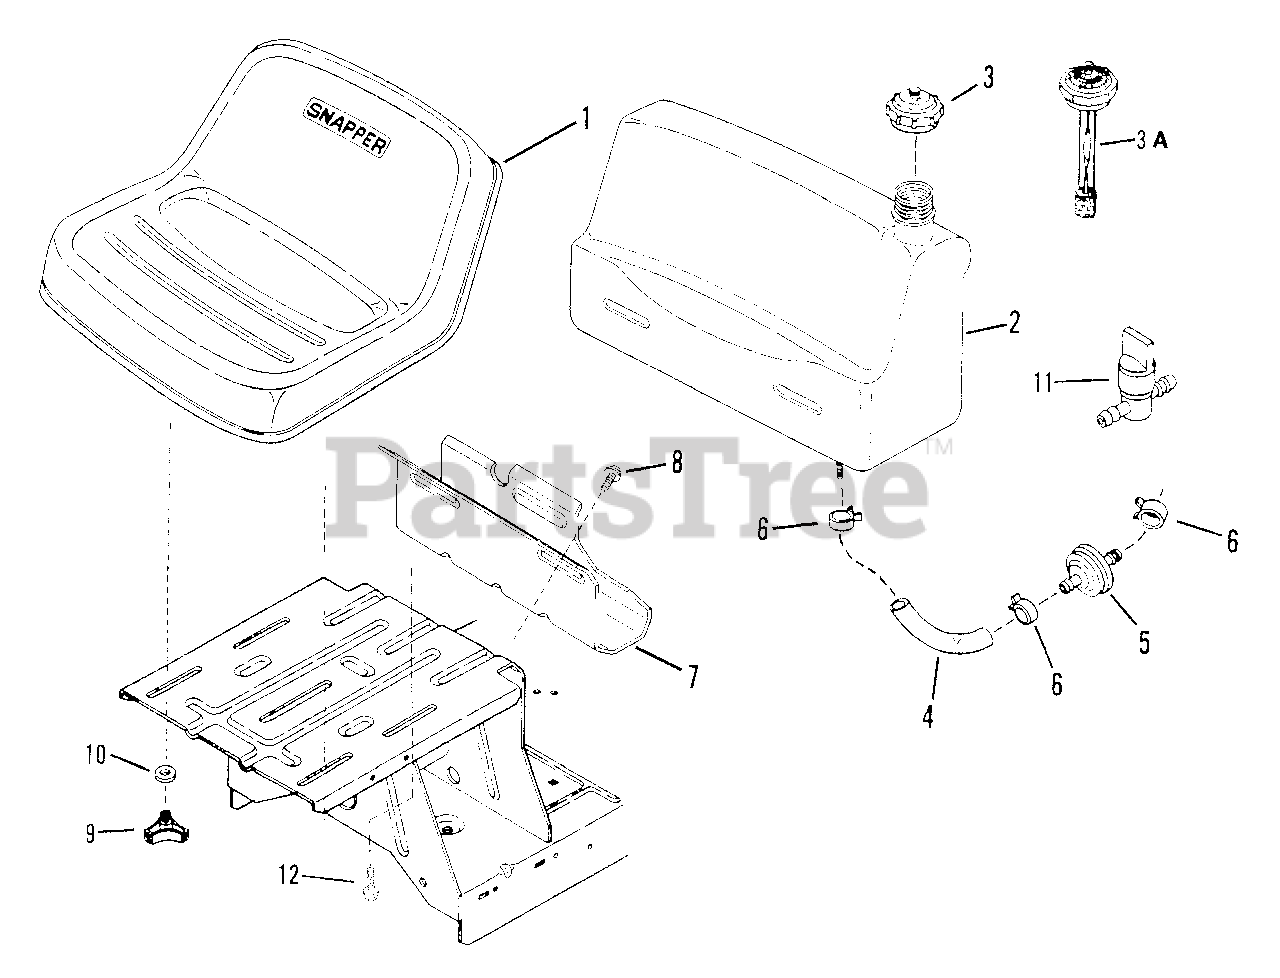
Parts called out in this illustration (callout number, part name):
1	SEAT, Operator
2	ASSEMBLY, Fuel Tank
3	CAP, Fuel Tank
3A	CAP, Fuel Tank/with Gauge
4	HOSE, Fuel (7" Long)
5	FILTER, Fuel (In-Line)
6	CLAMP, Fuel Line
7	BRACKET, Fuel Tank (Rear)
8	SCREW, 5/16-18 x 5/8" Self-Tapping
9	KNOB, Seat Adjusting
10	SPACER, 5/16
11	VALVE, Fuel Shut-Off (Metal)
12	BOLT, 5/16-18 x 1/2" Hex Flange Lock
